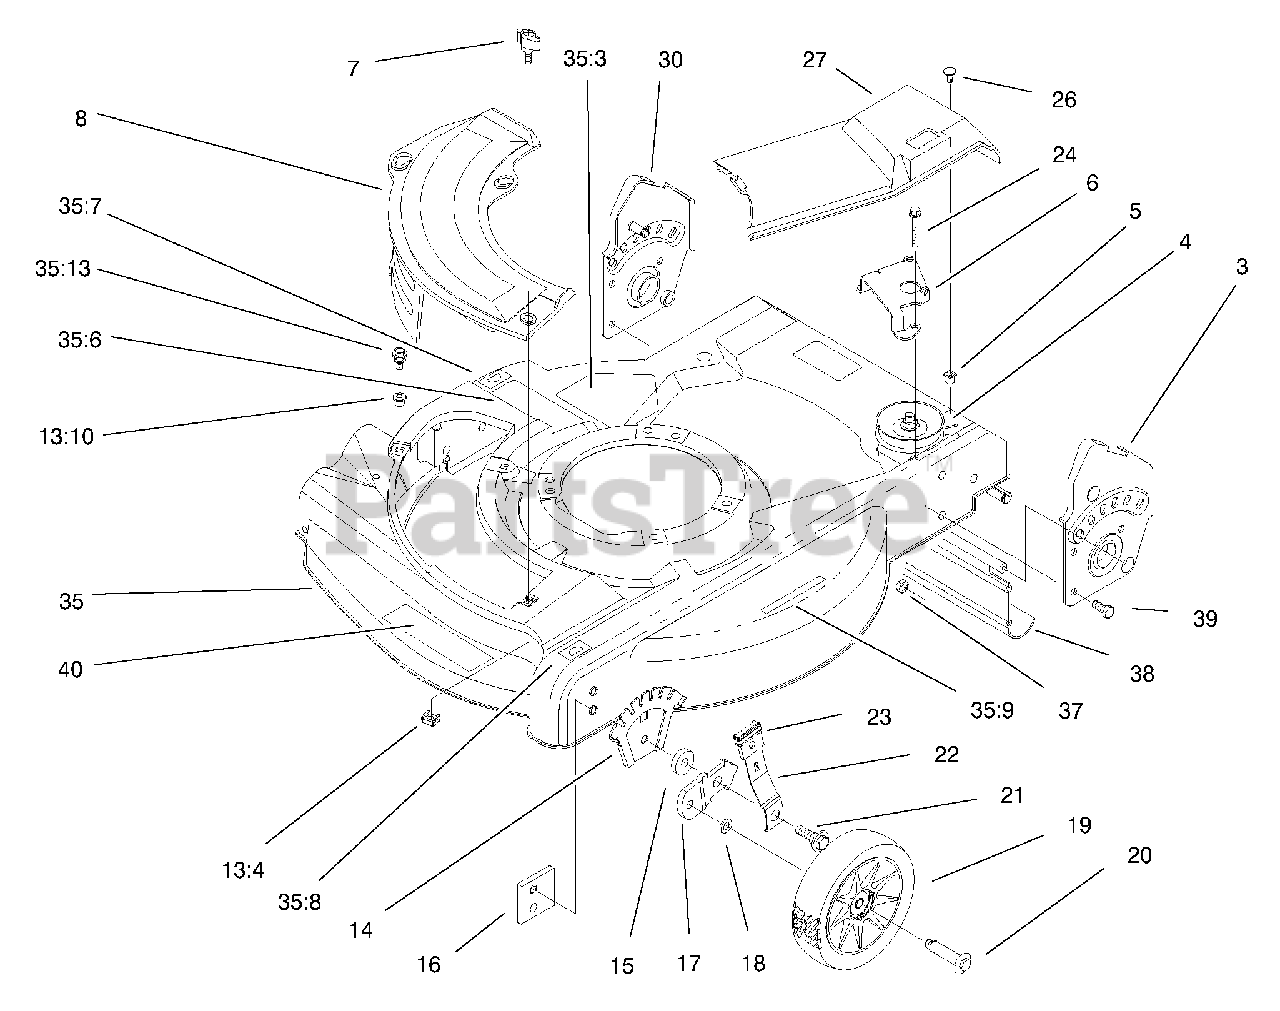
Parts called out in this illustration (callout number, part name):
3	LH Handle Bracket ASM
4	Gear Case Assembly
5	Grommet
6	Guide-Transmission
8	Plate-Mulch
14	Plate-Height Adjustment
15	Washer-Wheel
16	Plate-Baffle
17	Bracket-Wheel Height Adjustment
19	Wheel & Tire ASM
20	Bolt-Shoulder
21	Bolt-Shoulder
22	Arm-Front Spring
23	Knob-Lever, Height Adjustment
24	Screw-Thread Forming
27	Cover-Drive
30	RH Handle Bracket ASM
35	ASM-Hsg/Baffle w/Decals
35:3	Decal-Danger
35:4	Nut-Cage
35:6	Decal-Warning
35:7	Decal-HOC, RH
35:8	Decal-HOC, LH
35:9	Decal-Warning
35:10	Grommet-Plastic
35:13	Screw-Sems
37	Nut-Lock, NI
38	Shield-Trailing
39	Screw-HH
40	Decal-Deck
